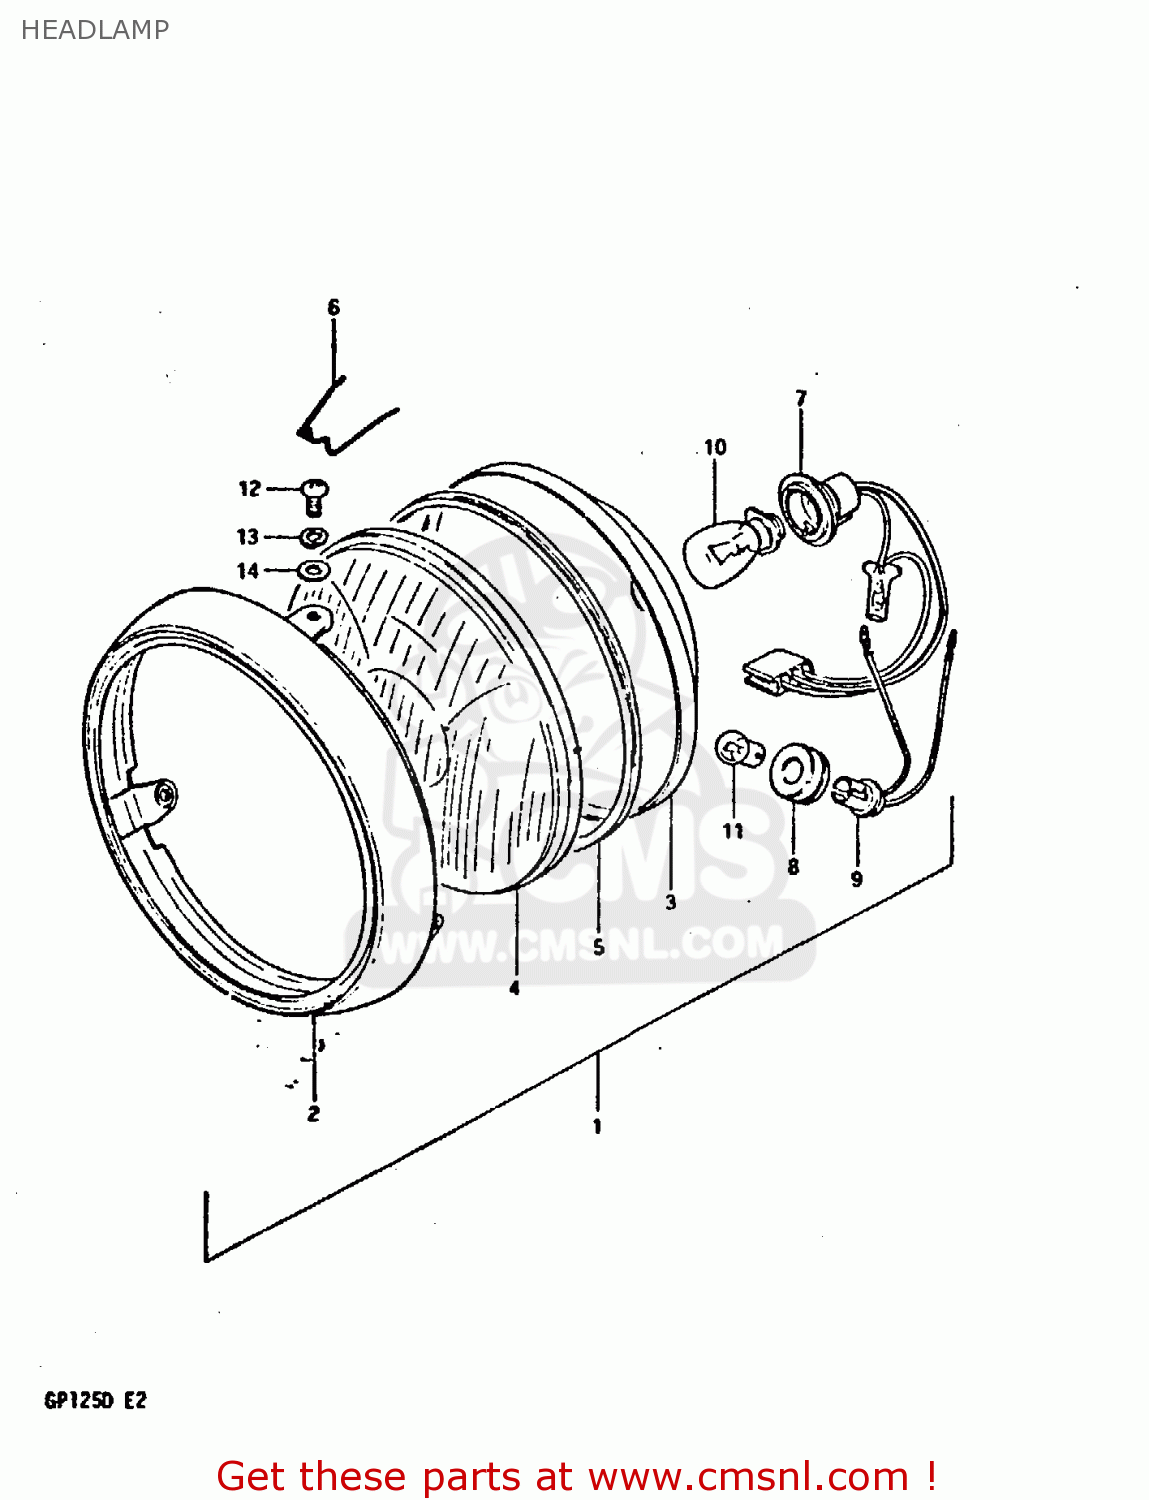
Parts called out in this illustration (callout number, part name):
1	HEADLAMP ASSY
2	RIM
3	REFLECTOR
4	LENS
5	GASKET (NAS)
6	SPRING
7	SOCKET
8	SEAL,PARKING BULB
9	SOCKET
10	BULB(6V25/25W,STANLEY,A7007)
11	BULB(6V/3W)
12	SCREW
13	LOCK WASHER
14	WASHER
